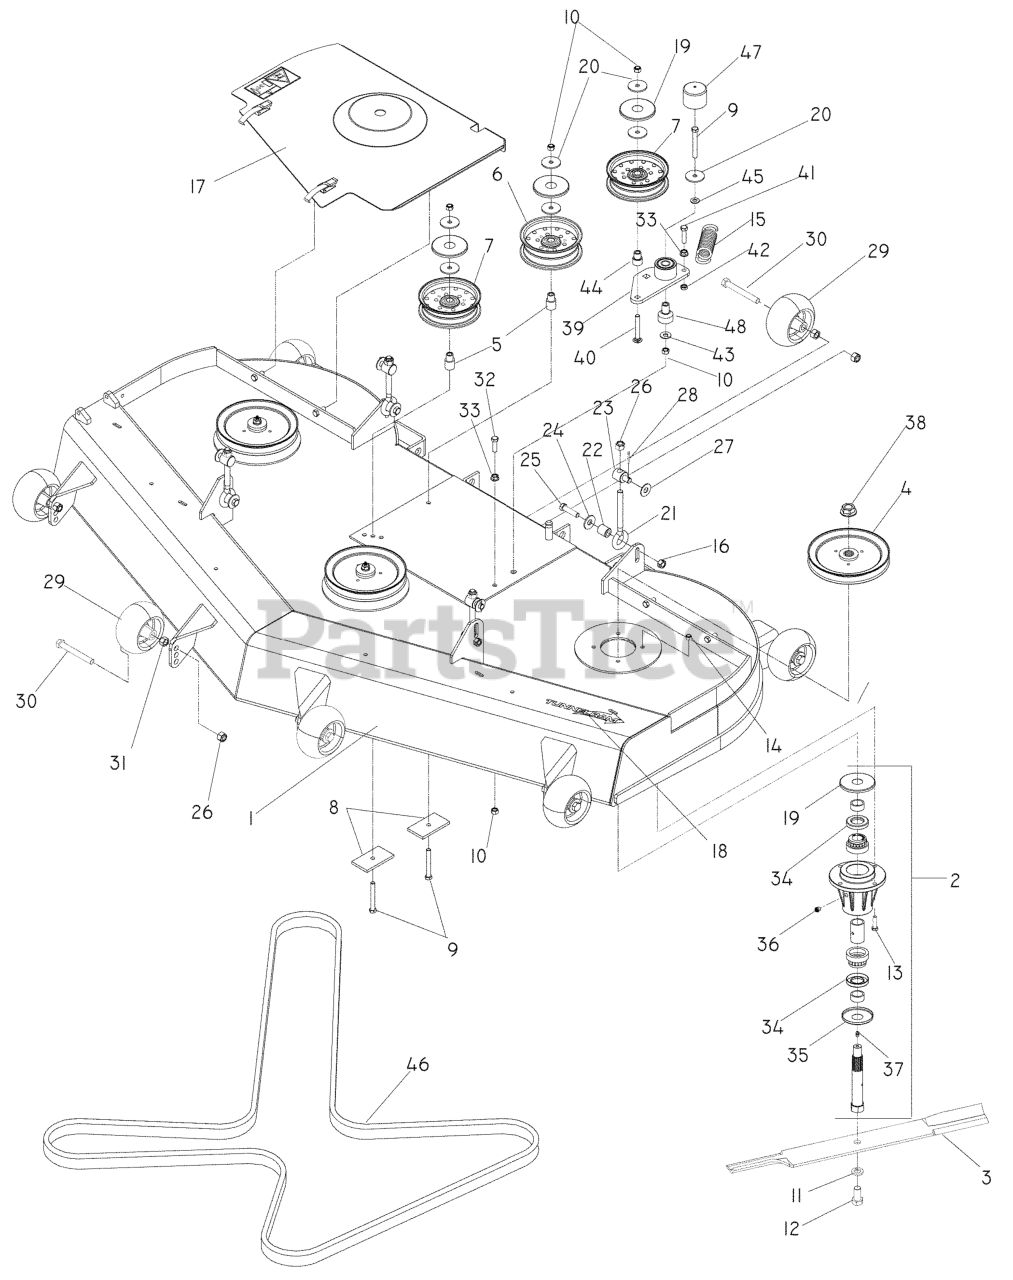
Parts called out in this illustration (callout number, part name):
1	DECK W/DECALS 72" HUS
2	HSG KIT 72 RIBBED
3	BLADE OEM - 25"
4	PULLEY, 72
5	IDLER BUSHING
6	IDLER PULLEY (TALL)
7	IDLER PULLEY
8	SUPPORT PLATE
9	HCS 3/8C X 3
10	NUT 3/8-16 NYLOC
11	LOCKWASHER 5/8
12	HCS 5/8F X 1 1/4
13	HCS 5/16C X 1 1/4
14	NUT 5/16 NYLOC
15	DECK SPRING
16	NUT 7/16C CENTERLOCK
17	72 BELT SHIELD ASM - RH
18	DECAL, TUNNEL RAM 8"
19	TOP DUST CAP
20	WASHER, 3/8 SPEC
24	SPRING WASHER - .50
25	HCS 7/16 - 14 X 1 3/4
26	NUT 1/2-13 HEX NYLOC ZD
27	WASHER 1/2 FLAT
28	PIN COTTER 1/8 X 1 ZD
29	GAUGE WHEEL
30	HCS 1/2-13 X 4 GR 5 ZD
31	NUT HEX 1/2
32	HCS 3/8C X 1 1/4 GR5
33	NUT 3/8C WHIZ
34	SHAFT SEAL
35	BOTTOM DUST CAP
36	PLUG-VENTED
37	ZERK
38	NUT FLANGE 3/4-16
39	ARM-IDLER W/BRG
40	RHSNB 3/8-16 X 2.75
41	HCS 3/8-16 X 1-1/2
42	NUT 3/8-16 HEX JAM
43	WASHER 3/8 FLAT
44	BUSHING, IDLER
45	WASHER 3/8 SAE FLAT
46	BELT, DECK 72"
47	CAP, VINYL
48	PIVOT, BEARING
